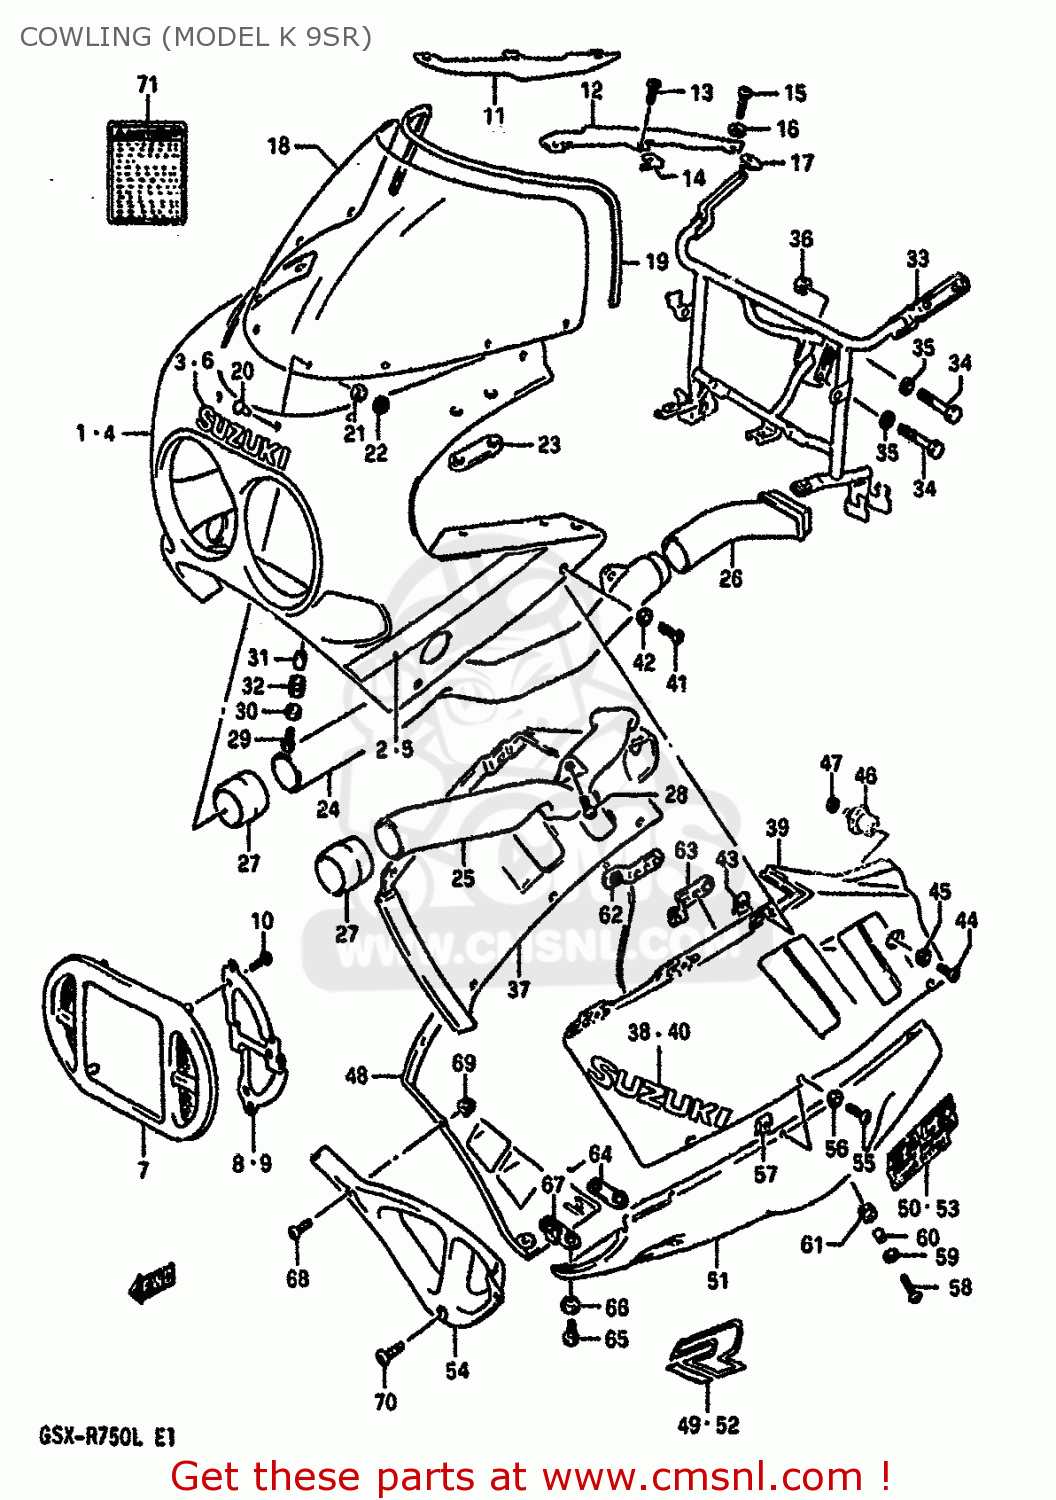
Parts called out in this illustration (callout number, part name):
1	BODY ASSEMBLY,COWLING
2	TAPE SET,COWLING,UPPER
3	EMBLEM,COWLING,UPPER (W)
4	BODY ASSY,COWLING (BLUE/WHITE)
5	TAPE SET,COWLING,UPPER
6	EMBLEM,COWLING,UPPER (W)
7	COVER,FRONT (WHITE)
8	PLATE,COVER RH
9	PLATE,COVER LH
10	TAPPING SCREW 4X10/A
11	PANEL,COWLING UPPER,RIGHT
12	COVER,COWLING,LEFT
13	SCREW(5X10)
14	NUT
15	SCREW(5X14)
16	WASHER(5.2X11X1)
17	NUT
18	WINDSCREEN
19	MOLDING
20	PIN,WINDSCREEN
21	CUSHION
22	NUT
23	CUSHION,RR VIEW MIRRORR
24	PIPE,AIR INTAKE,FRONT
25	PIPE,AIR INTAKE,FRONT
26	PIPE,AIR INTAKE RR,R
27	JOINT,AIR INTAKE
28	SCREW
29	SCREW(6X20)
30	WASHER(6.5X18X1)
31	SPACER
32	CUSHION
33	BRACE,COWLING
34	BOLT
35	WASHER,LOCK,8.
36	NUT ,8MM
37	COVER,COWLING SIDE,RIGHT
38	EMBLEM
39	COVER,COWLING SIDE,LEFT
40	EMBLEM
41	SCREW(5X18)
42	WASHER(5.2X14X1.5)
43	NUT,HEADLAMP HOUSING,UPPER
44	SCREW(6X12)
45	WASHER(6.3X16X1.5)
46	CUSHION,COWLING
47	WASHER,LOCK
48	COWLING,UNDER RH (BLUE/WHITE)
49	EMBLEM,COWLING UNDER
50	EMBLEM
51	COWLING,UNDER LH (BLUE/WHITE)
52	EMBLEM,COWLING UNDER
53	EMBLEM
54	COWLING,UNDER,CENTER
55	SCREW(5X18)
56	WASHER(5.2X14X1.5)
57	NUT,HEADLAMP HOUSING,UPPER
58	SCREW(6X20)
59	WASHER(6.5X18X1)
60	SPACER
61	CUSHION
62	BRACKET
63	BRACE,COWLING UNDER,LH
64	BRACE,COWLING LWR COVER RR
65	SCREW(6X16)
66	WASHER(6.3X16X1.5)
67	BRACE,COWLING LWR COVER
68	SCREW(5X14)
69	NUT
70	SCREW(6X16)
71	LABEL (WARNING SCREEN)
